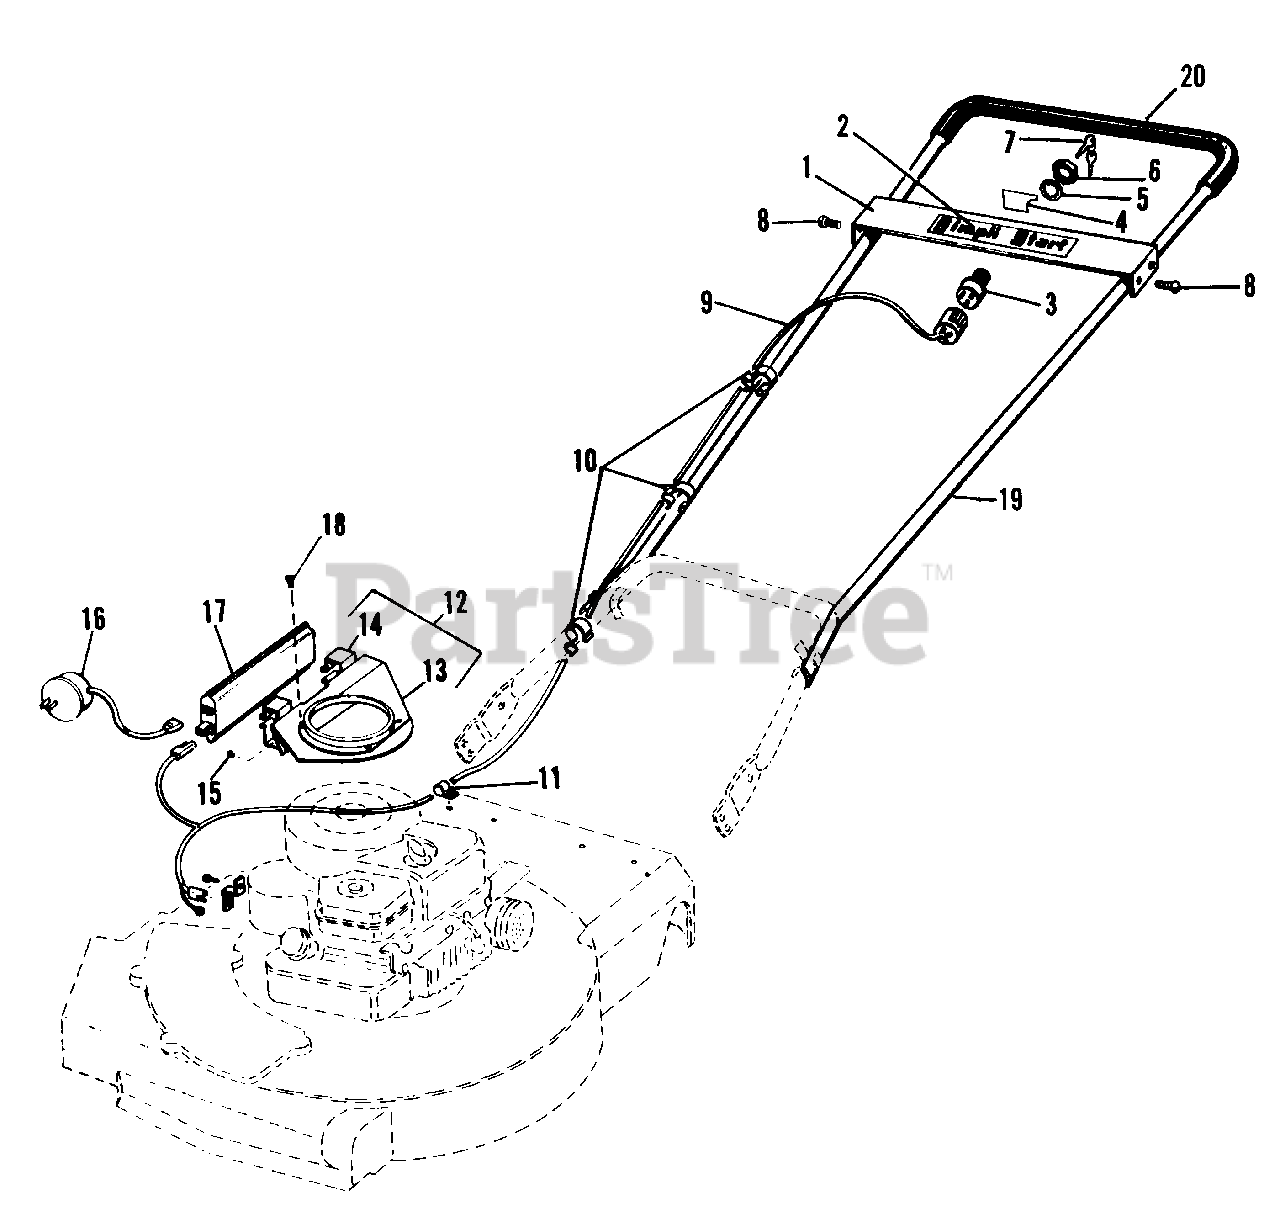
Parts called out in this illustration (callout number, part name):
1	MOUNTING PANEL, Switch
2	DECAL, Simplicity Start
3	SWITCH, Starting
4	DECAL, Starting
5	LOCKWASHER, Inter. Tooth,
6	NUT, Hex Special
7	KEY & RING ASSY (Service
8	SCREW, Self Thd., 1/4-20 x 3/8
9	HARNESS ASSY
10	CLAMP, Cable
11	CLAMP, Cable
12	SUPPORT ASSY, Ring
13	SUPPORT, Ring
14	CLIP, Battery
15	RIVET, Clip
16	CHARGER, Battery
18	SCREW, Thd. Form #4-40 x 1/4
19	HANDLE, Upper
20	TUBING, Handle
